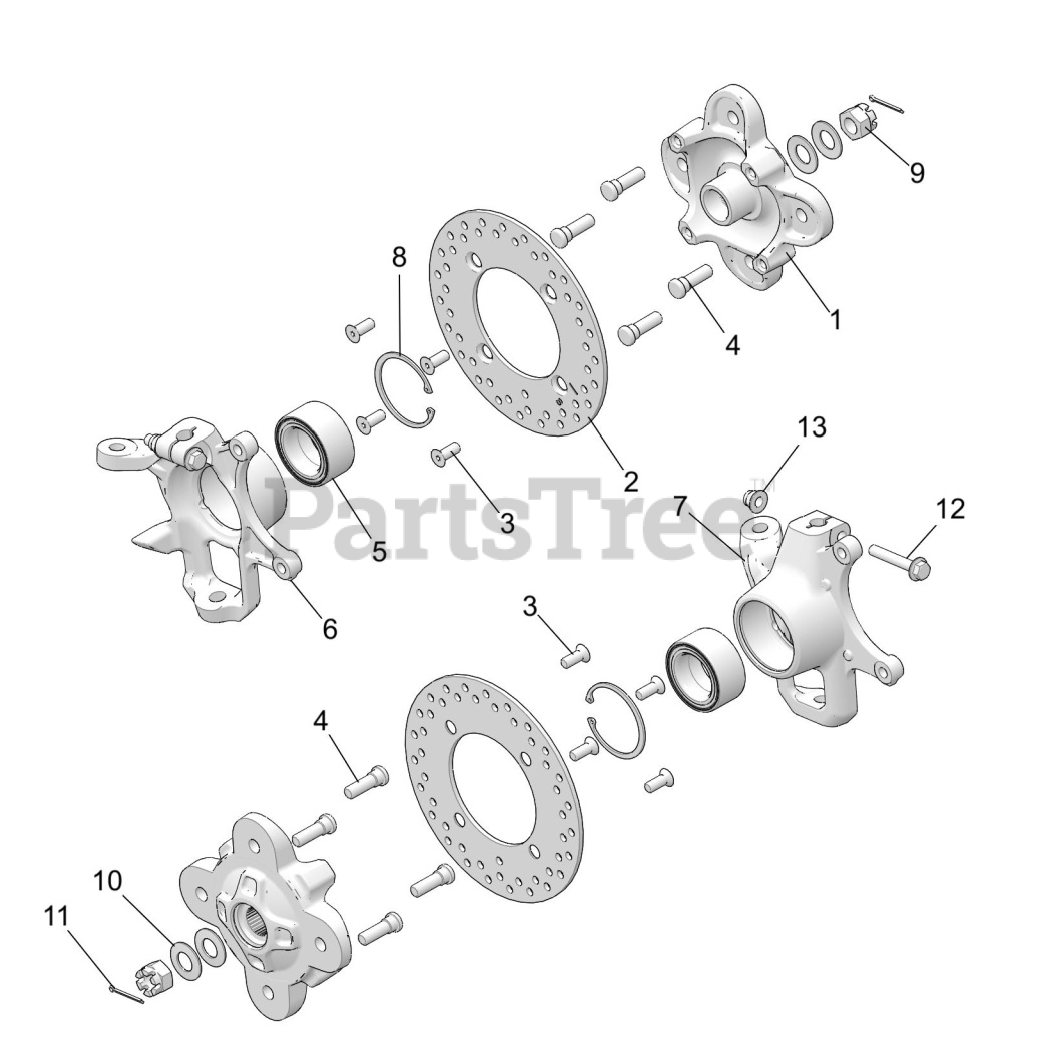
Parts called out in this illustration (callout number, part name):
1	HUB-WHEEL,FRONT MACH,BLK
2	ROTOR,BRAKE
3	SCR-M10X1.5X20 8.8 TXCS FL ZOD
4	STUD-WHEEL,M12-1.5
5	BEARING-BALL,SEALED,44X72X33.1
6	KNUCKLE-FRONT,LH
7	KNUCKLE-FRONT,RH
8	RING, RETAINING, INTERNAL
9	NUT-M18X1.5,CASTLE,ZINC/YELLOW
10	WASHER, CONE
11	PIN, COTTER
12	SCR-HXFL-M10X1.25X60 10.9 ZOD
13	NUT-M10X1.25,FLG,NYLOC-OLIVE D
